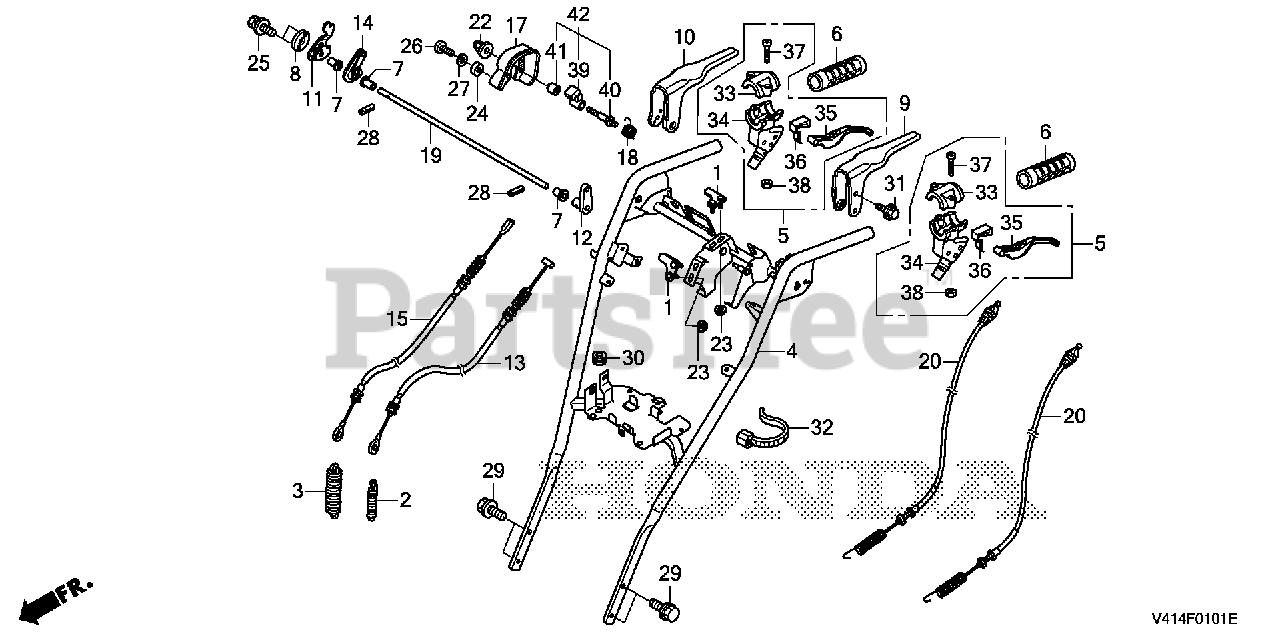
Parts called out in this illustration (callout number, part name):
1	BRACKET, STOPPER
2	SPRING, WHEEL TENSION
3	SPRING, AUGER TENSIONER
4	PIPE, HANDLE (UPPER) *NH105* (MAT BLACK)
5	LEVER ASSY., STEERING
6	GRIP, HANDLE
7	BUSHING (A)
8	BOSS, CLUTCH SPACER
9	LEVER, CLUTCH
10	LEVER, AUGER CLUTCH
11	BOSS, R. CLUTCH LEVER
12	BOSS, CLUTCH LEVER
13	CABLE, CLUTCH
14	BOSS, CAM LOCK
15	CABLE, AUGER CLUTCH
16	RATCHET, LEVER
17	COVER, RATCHET
18	SPRING, RATCHET
19	SHAFT, CLUTCH LEVER
20	CABLE, STEERING
21	BOLT, PIVOT (6MM)
22	NUT, FLANGE CAP (6MM)
23	NUT, NYLON LOCK (6MM)
24	COLLAR, FUEL PETCOCK
25	BOLT-WASHER (6X16)
26	SCREW, PAN (4X12)
27	WASHER, PLAIN (4MM)
28	PIN, SPRING (4X20)
29	BOLT, FLANGE (8X16)
30	GROMMET, RESERVE TANK
31	BOLT, FLANGE (6X12)
32	BAND, WIRE (165MM) (BLACK)
33	CLAMP (NA USE ALT:53175-V45-A01)
34	BRACKET (NA USE ALT:53175-V45-A01)
35	LEVER (NA USE ALT:53175-V45-A01)
36	PIVOT (NA USE ALT:53175-V45-A01)
37	BOLT, SOCKET (5X25) (NA USE ALT:53175-V45-A01)
38	NUT, NYLON LOCK (5MM) (NA USE ALT:53175-V45-A01)
39	RATCHET, LEVER
40	BOLT, RATCHET LEVER
41	COLLAR, RATCHET COVER
42	RATCHET KIT
